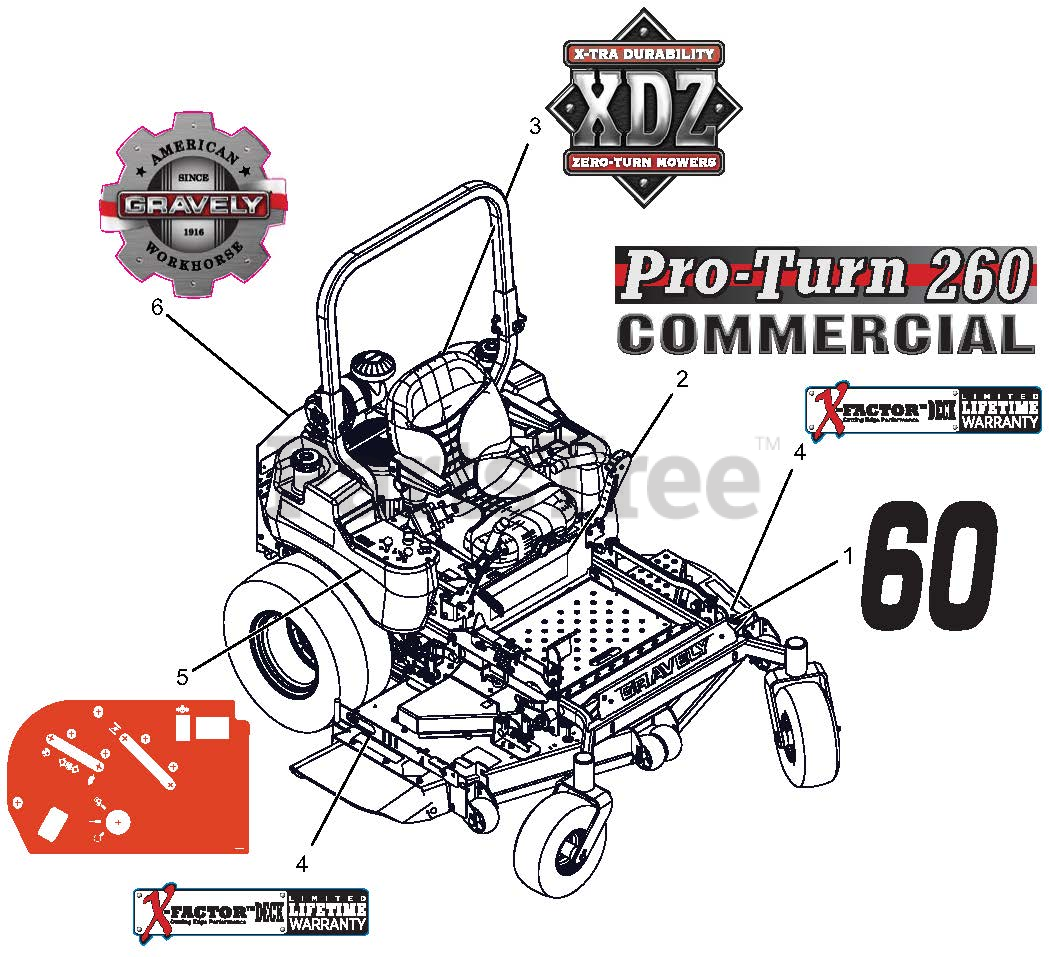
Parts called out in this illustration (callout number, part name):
1	DECAL, 60"
2	DECAL, PROTURN 260
3	DECAL, XDZ
4	DECAL, X-FACTOR DECK
5	DECAL, CONTROL PANEL NON-EFI
6	DECAL, GRAVELY HERITAGE-LARGE
